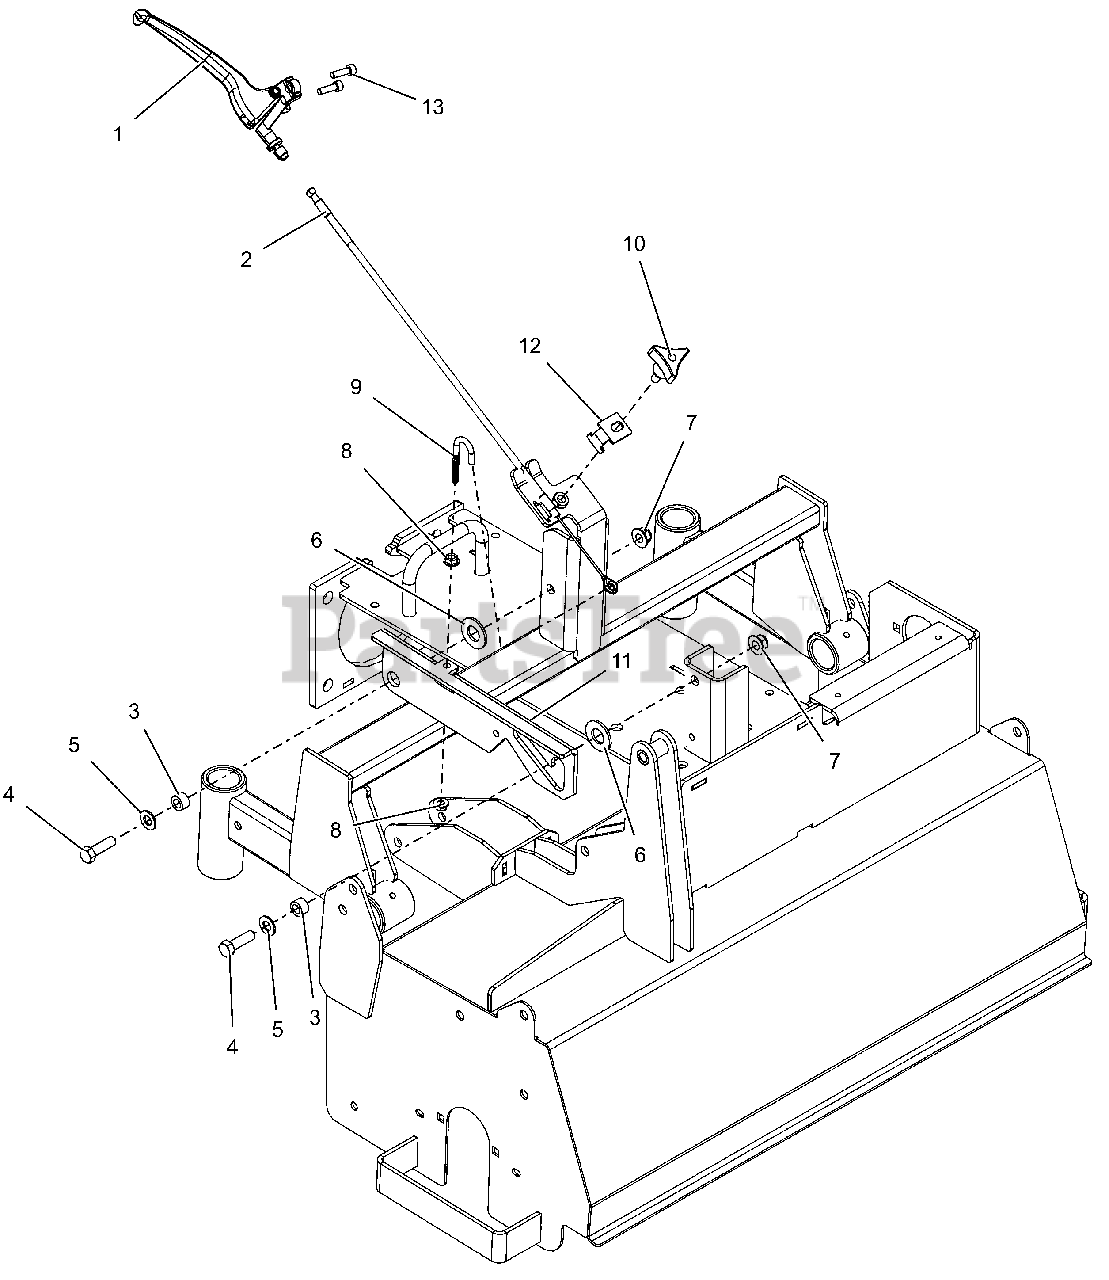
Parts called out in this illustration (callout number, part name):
1	HANDLE, ANGLE CONTROL
2	CABLE ASSY, BRUSH
3	BSHG-SLV .377X.624X.370
4	BLT, HEX .38-16X1.25 G5 ZCC
5	WSHR,FLT .406X.812X.065 ZCC
6	WSHRFLT 5/8SAE CARBHARD FBP
7	NUT,NYL-FLG .38-16 GF ZCC
8	NUT-SPNLK-FLG .25-20 ZC120
9	BLT, J-HOOK .25-20X2.31 ZCC
10	KNOB,WING STUD 5/16-18 X .75
11	EAR, HANDLE LOCK
12	BRKT, CABLE CLAMP (BLACK)
13	SCR, SKH M6-1 X 20 GR10.9 ZCC
